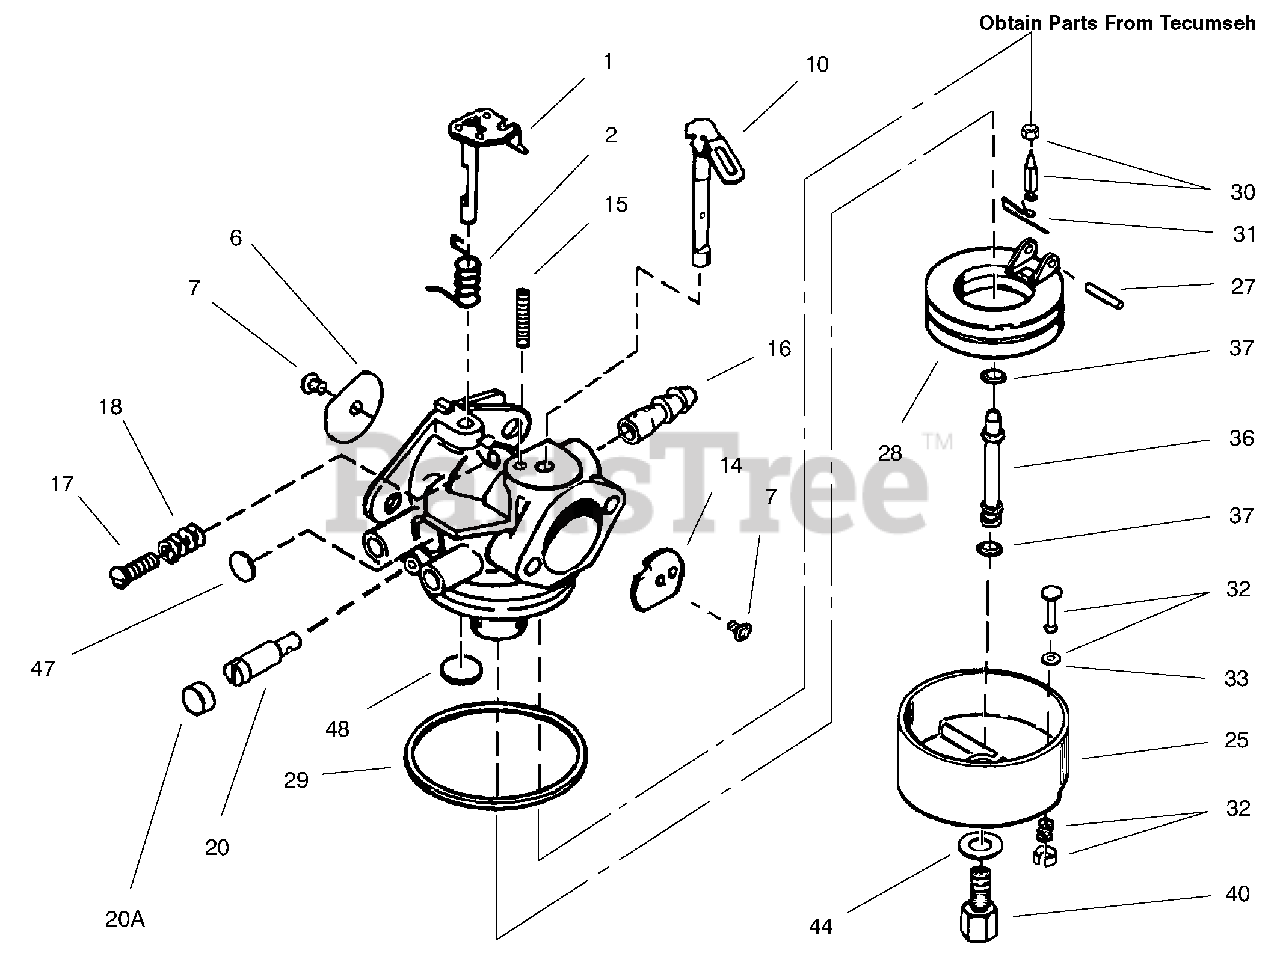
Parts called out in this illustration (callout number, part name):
1	Throttle Shaft and Lever ASM
2	Spring-Return, Throttle
6	Shutter-Throttle
7	Screw-Shutter
10	Choke Shaft and Lever ASM
14	Shutter-Choke
15	Spring-Positioning, Choke
16	Fitting-Fuel
17	Throttle Crack Screw / Idle Speed Screw
18	Spring-Tension
20	Screw-Restrictor, Idle
21	Cap-Screw, Idle Restrictor
25	Float Bowl Assembly (Incl. Ref. #32 & 33)
27	Shaft-Float
28	Float
29	O-Ring-Bowl, Float
30	Inlet Needle, Seat and Clip Asm (Incl. Ref. #31)
31	Clip-Spring
32	Drain Assembly (Incl. Ref. #33)
33	Gasket-Plunger, Drain
36	Tube-Nozzle, Main
37	O-Ring-Nozzle Tube, Main
40	Nut-High Speed, Bowl
44	Washer-Bowl Nut
47	Plug-Welch, Idle Mixture Well
48	Plug-Welch, Atmospheric Vent
